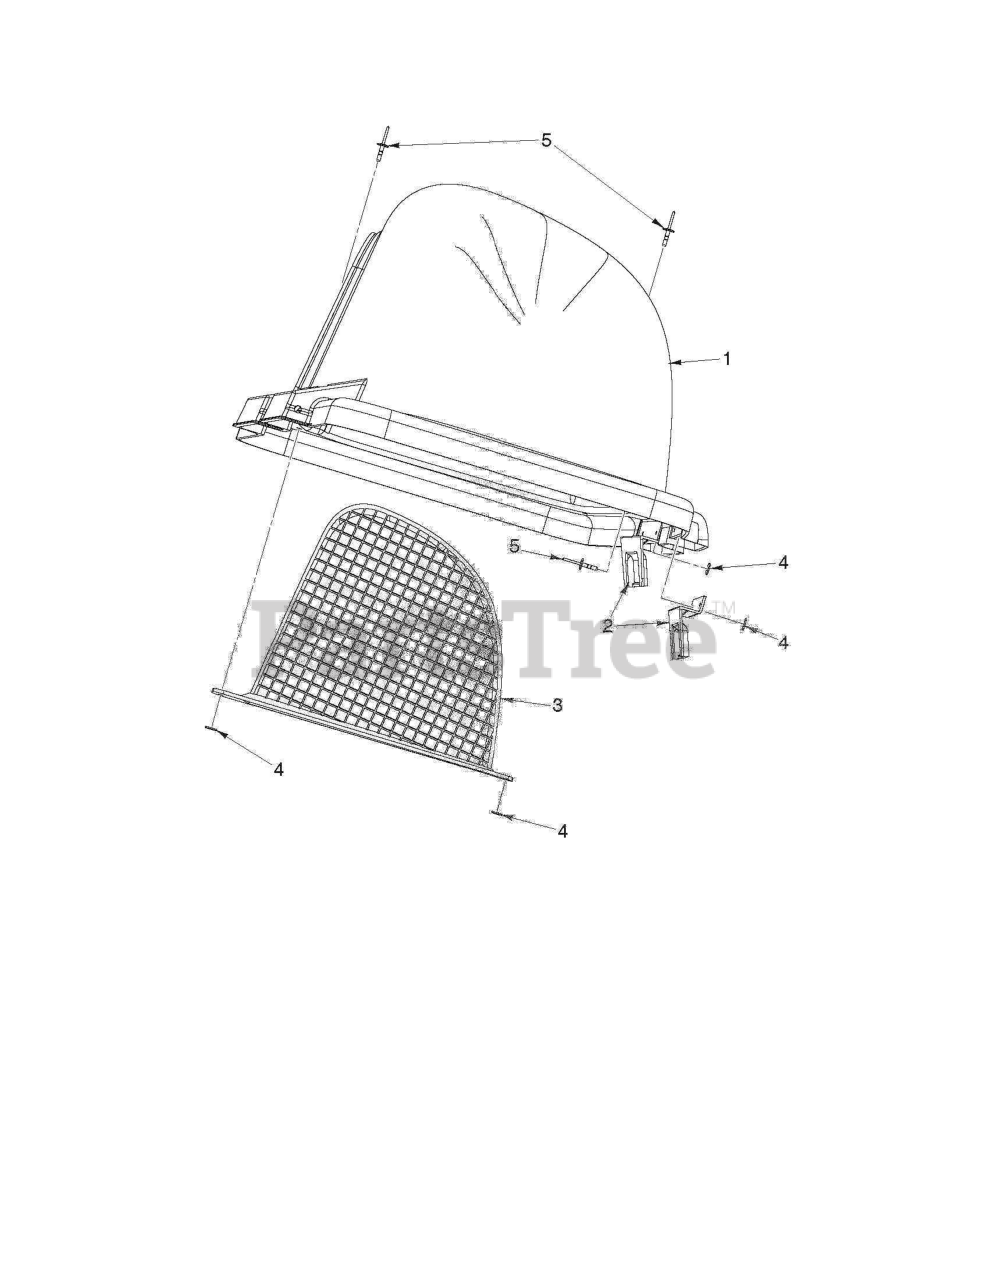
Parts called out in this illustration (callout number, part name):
1	Covers
2	LATCH CER38
3	SCREEN.COVER.BAGGER
4	WASHER, .196 X .625 X 16 GA
5	RIVET RIVET.3/16 X.731 L.625HE
